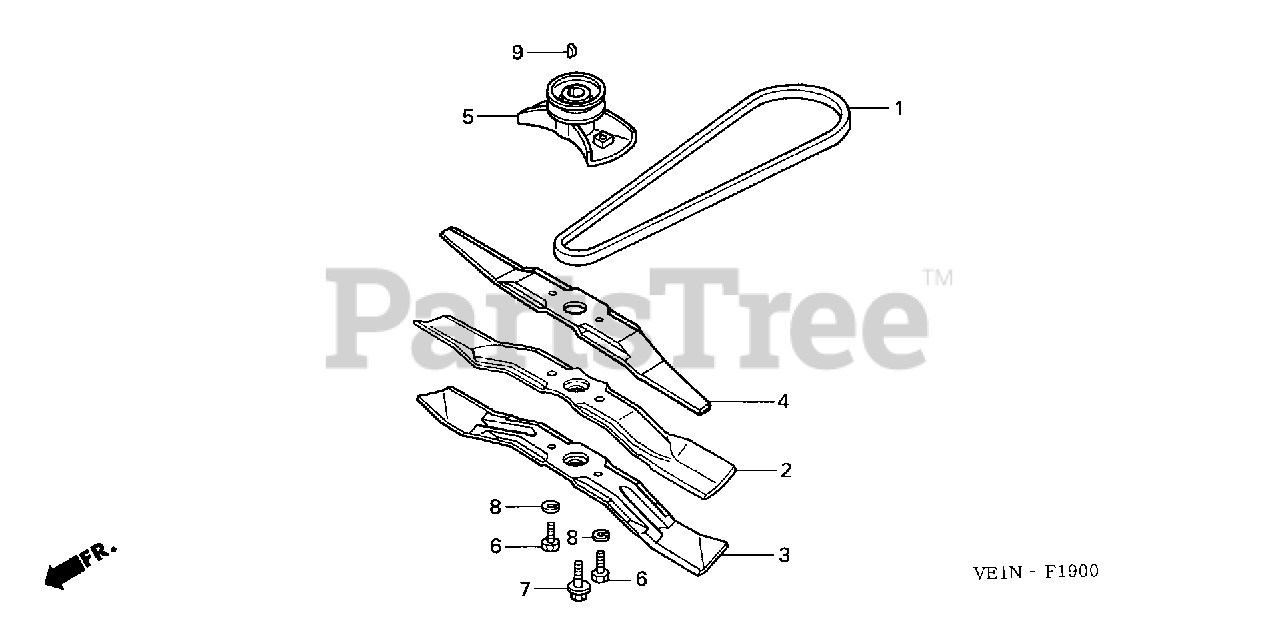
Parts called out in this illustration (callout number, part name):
1	V-BELT (3L-36.3)
2	BLADE, ROTARY (BAGGING)
3	BLADE, ROTARY
3	BLADE, ROTARY (PCD=88MM)
4	BLADE, ROTARY (UPPER) (PCD=88MM)
5	HOLDER KIT, BLADE
5	HOLDER, BLADE
6	BOLT, HEX. (10X20)
7	BOLT, FLANGE (3/8-24X1")
8	WASHER, SPRING (10MM)
9	KEY, WOODRUFF (3/16X5/8)
